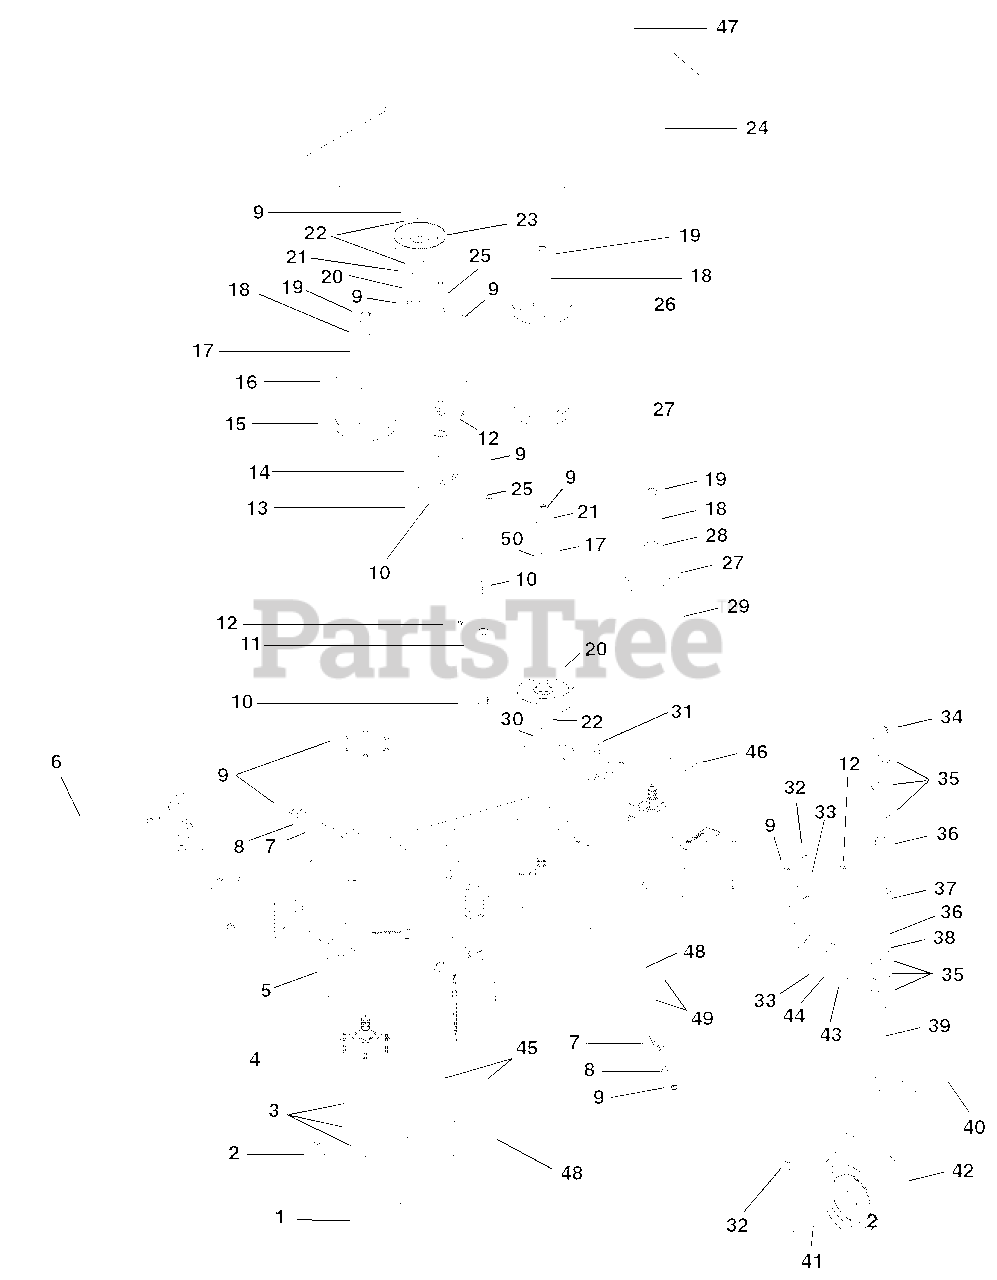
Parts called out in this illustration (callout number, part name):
1	Bolt, .625-11 x 2.00 Hex 8
2	Blade, 16.500 Lo-Lift
3	Washer, Blade
4	Assembly, Spindle Housing
5	48" Gravely Gear Deck with Decals
6	Discharge Shield Assembly
7	Spring, COM 1.22 x .162 x 2.50
8	Keeper, Spring
9	Locknut, .38-16 Nyloc
10	Bearing, Flange M10 x M25 x M27 Fluted
11	Weldment, Idler Arm w/Offset
12	Fitting, .25-28 STRGT Grease Zerk
13	Bolt, .38-16 x 2.50 Hex Grade 5
14	Weldment, Idler
15	Pulley, Spline Spindle Offset
16	Belt, HB 51.4 Elbow AMD
17	J-Bolt, .375-16 x 7.88
18	Washer, .75 x 1.313 x .113
19	Locknut, .75-16 Crown
20	Pulley, Flat 5.00 x .375 w/BRG
21	Washer, Flat .375 x 1.50 x .063
22	Washer, .406 x .813 x .065 Flat
23	Pulley, V-Belt 5.0
24	Weldment, 48" Belt Shield Gravely
25	Bracket, Idler
26	Pulley, Spline Spindle Offset
27	Pulley, Spline Spindle SH
28	Spacer, 1.500 x 1.000 x .510
29	Belt, HB Wrapped 83.2
30	Bolt, .38-16 x 2.75 Grade 5
31	Bolt, Hex .625-11 1.5 Grade 8
32	Locknut, .50-13 Nyloc
33	Washer, .438 Regular Flat
34	Pin, LNC .438 x 2.00
35	C-Spacer, 1.00 x 1.77 x .500
36	Bearing, Flange 1.00 x 1.25 x 1.00
37	Weldment, Strut Front FXWLK w/Gravely Paint
38	Bushing, 1.03 x 1.50 x .179
39	Weldment, Caster Yoke w/Gravely Paint
40	Bolt, .50-13 x 5.50 Hex Grade 5
41	Tube, Caster Axle
42	Assembly, Wheel and Tire 9 x 3.5
43	Bolt, .50-13 x 1.25 Hex 5
44	Washer, .500 Medium Spring Lock
45	Bolt, .375-16 x 3.50 Round Head Square Neck Grade 5
46	Trim, 1/4" Trim-LOK
47	Knob, .375 x 1.25-4 Prong
48	Bolt, .38-16 x 1.00 Round Head Square Neck Grade 5
49	Bolt, .50-13 x 1.50 Round Head Square Neck Grade 5
50	Bushing, .380 x 1.00 x .410
